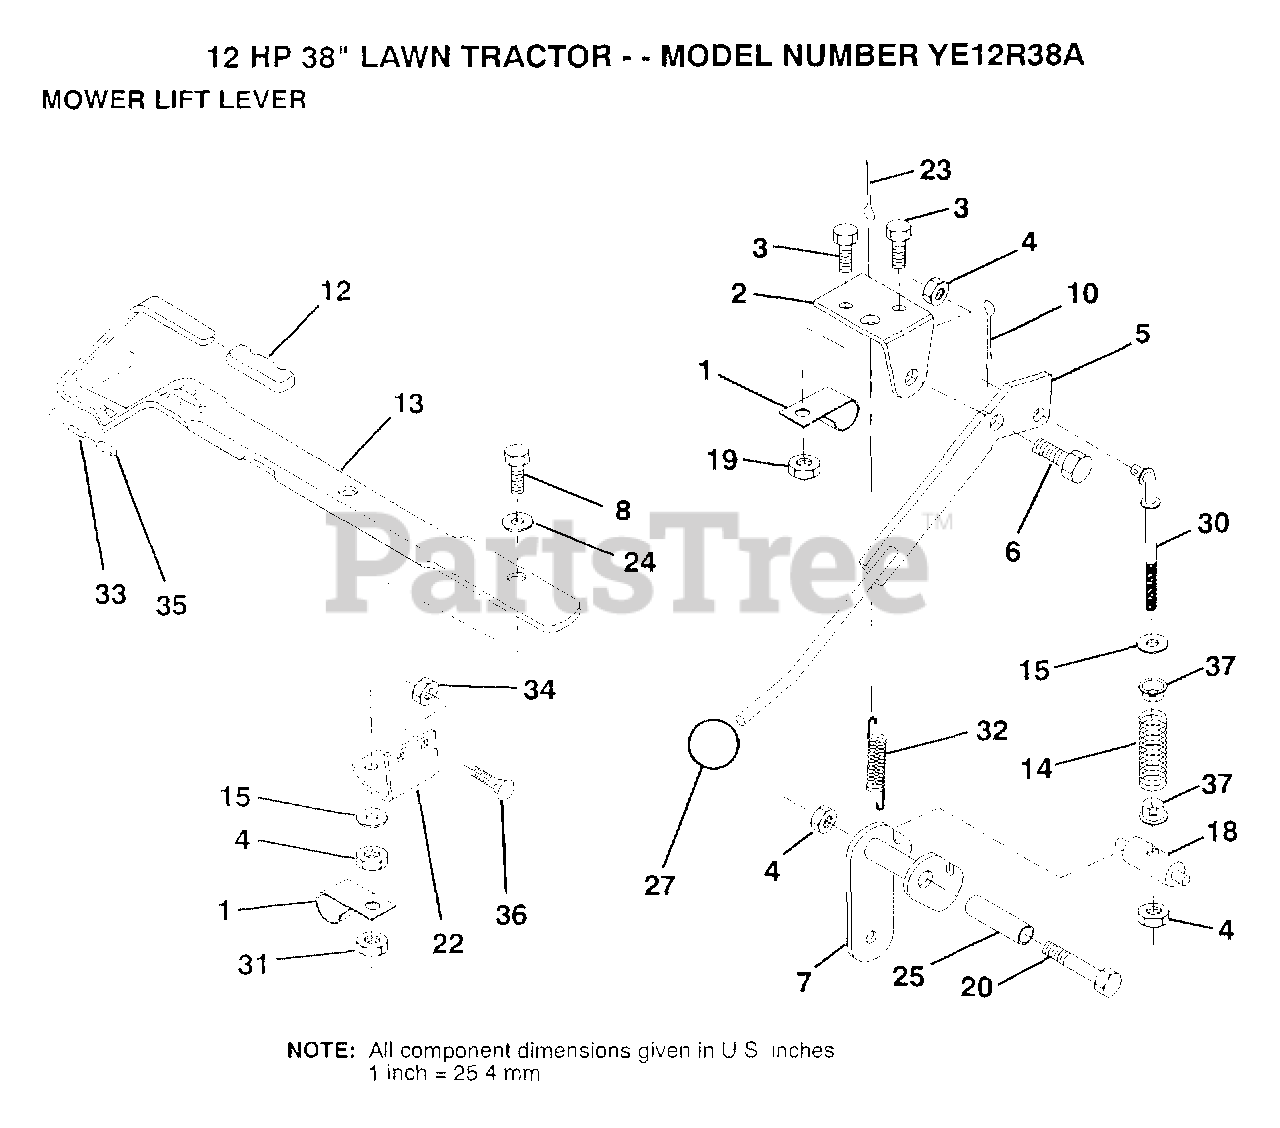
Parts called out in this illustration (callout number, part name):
1	"CLIP,INSULATOR"
2	BRKT CLUTCH
3	BOLT
5	CLUTCH LEVER AS
6	"BOLT, SHOULDER LT"
7	MWR CLUT ARM ASM
8	BOLT
10	COTTER PIN
12	LIFT LEVER HANDLE
13	LIFT HANDLE ASM
14	COMP CLUTCH SPRNG
15	WASHER HYT
18	TRUNNION
20	BOLT
22	LIFT LEVER BRKT
24	WASHER
25	TUBE SPACER
27	KNOB
30	ROD TENSION CLUTC
31	LOCKNUT
32	SPRING EXT
35	VINYL CAP RED
36	BOLT
